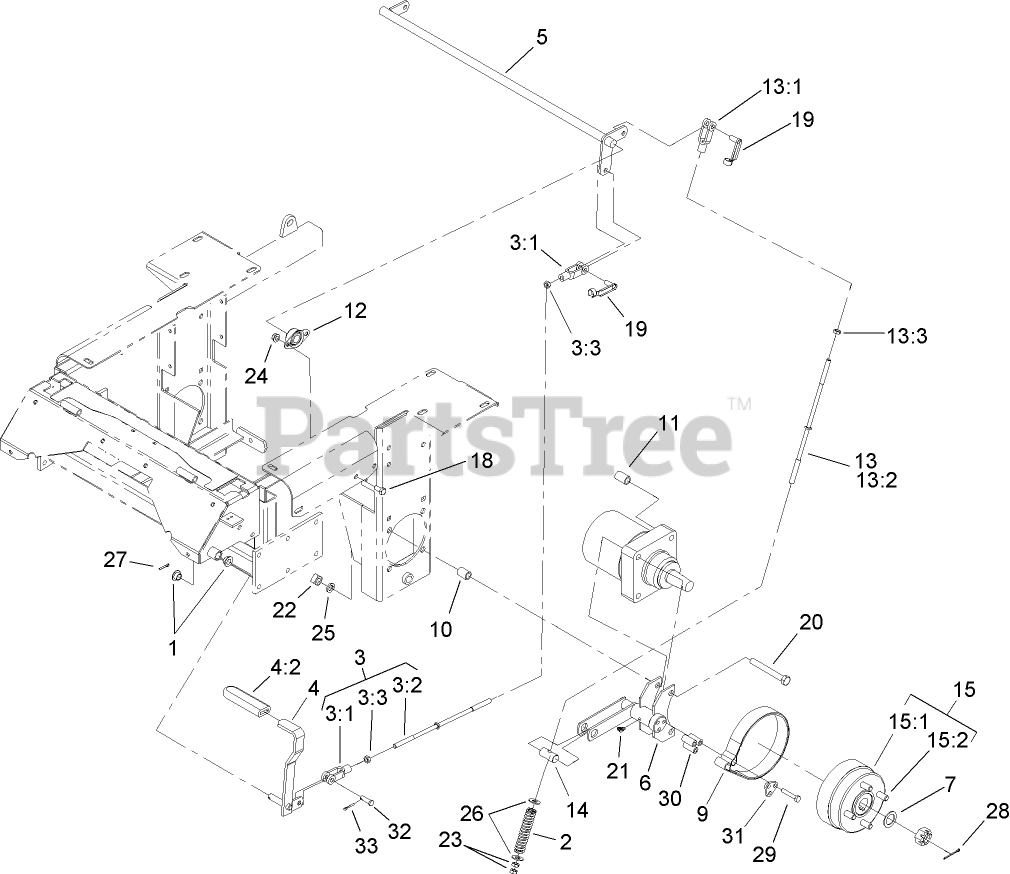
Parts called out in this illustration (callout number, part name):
1	BEARING-CONTROL
2	SPRING-BRAKE
3	Brake Rod And Yoke ASM
3:1	YOKE-LINKAGE, BRAKE
3:2	ROD-BRAKE
3:3	NUT-HEX
4	BRAKE LEVER ASM
4:2	GRIP-LEVER
5	SHAFT-BRAKE
6	BRACKET-BRAKE
7	WASHER-SPACER
9	BAND-BRAKE
10	SPACER-WHEEL, SHORT
11	SPACER-WHEEL, LONG
12	BEARING-FLANGE, SIDE
13	Brake Rod And Yoke ASM
13:1	YOKE-LINKAGE, BRAKE
13:2	ROD-BRAKE
13:3	NUT-HEX
14	PIN-TRUNION
15	WHEEL HUB ASM
15:1	HUB-WHEEL
15:2	STUD-WHEEL
18	SCREW-HH
19	Pin-Spring, Clevis
20	SCREW-HH
21	FITTING-GREASE
22	NUT-SQUARE
23	NUT-HEX
24	NUT-HHF, WHIZ
25	WASHER-LOCK
26	WASHER-FLAT
27	PIN-COTTER
28	PIN-COTTER
29	SCREW-HH
30	SPACER
31	RETAINER-BAND, BRAKE
32	PIN-CLEVIS
33	PIN-COTTER
